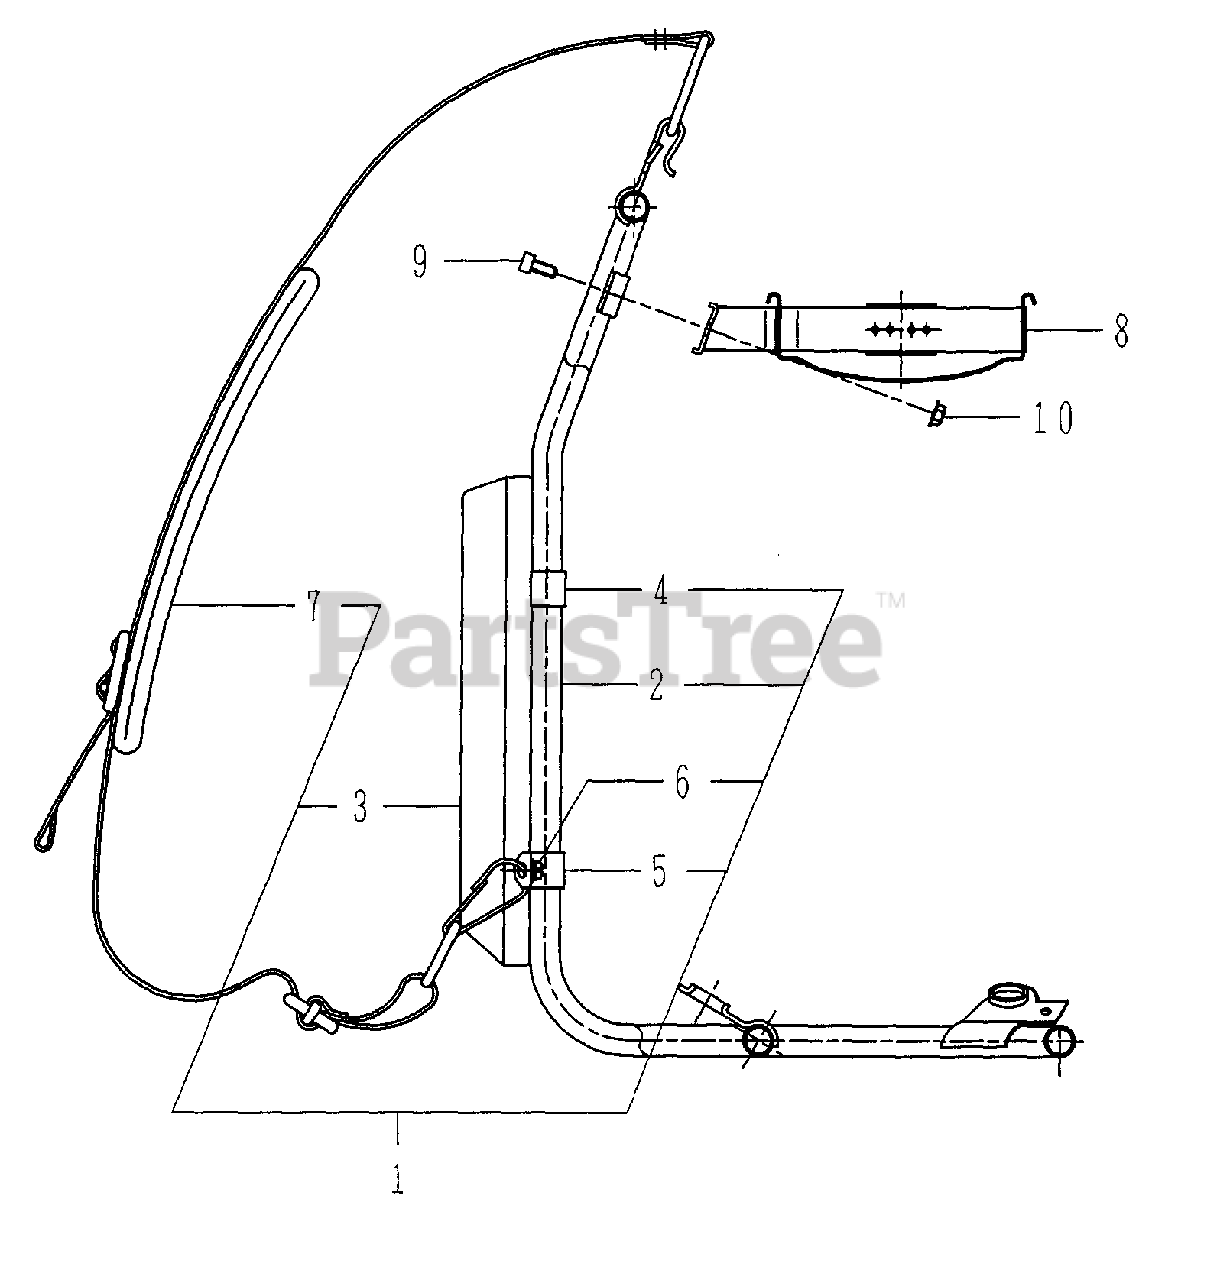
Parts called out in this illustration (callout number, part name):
1	BACKPACK FRAME ASSY
2	FRAME, BACKPACK
3	PAD
4	CLAMP - UPPER
5	CLAMP - LOWER
6	SCREW
7	HARNESS ASSY
8	BRACKET, FUEL TANK
9	BOLT
10	NUT
